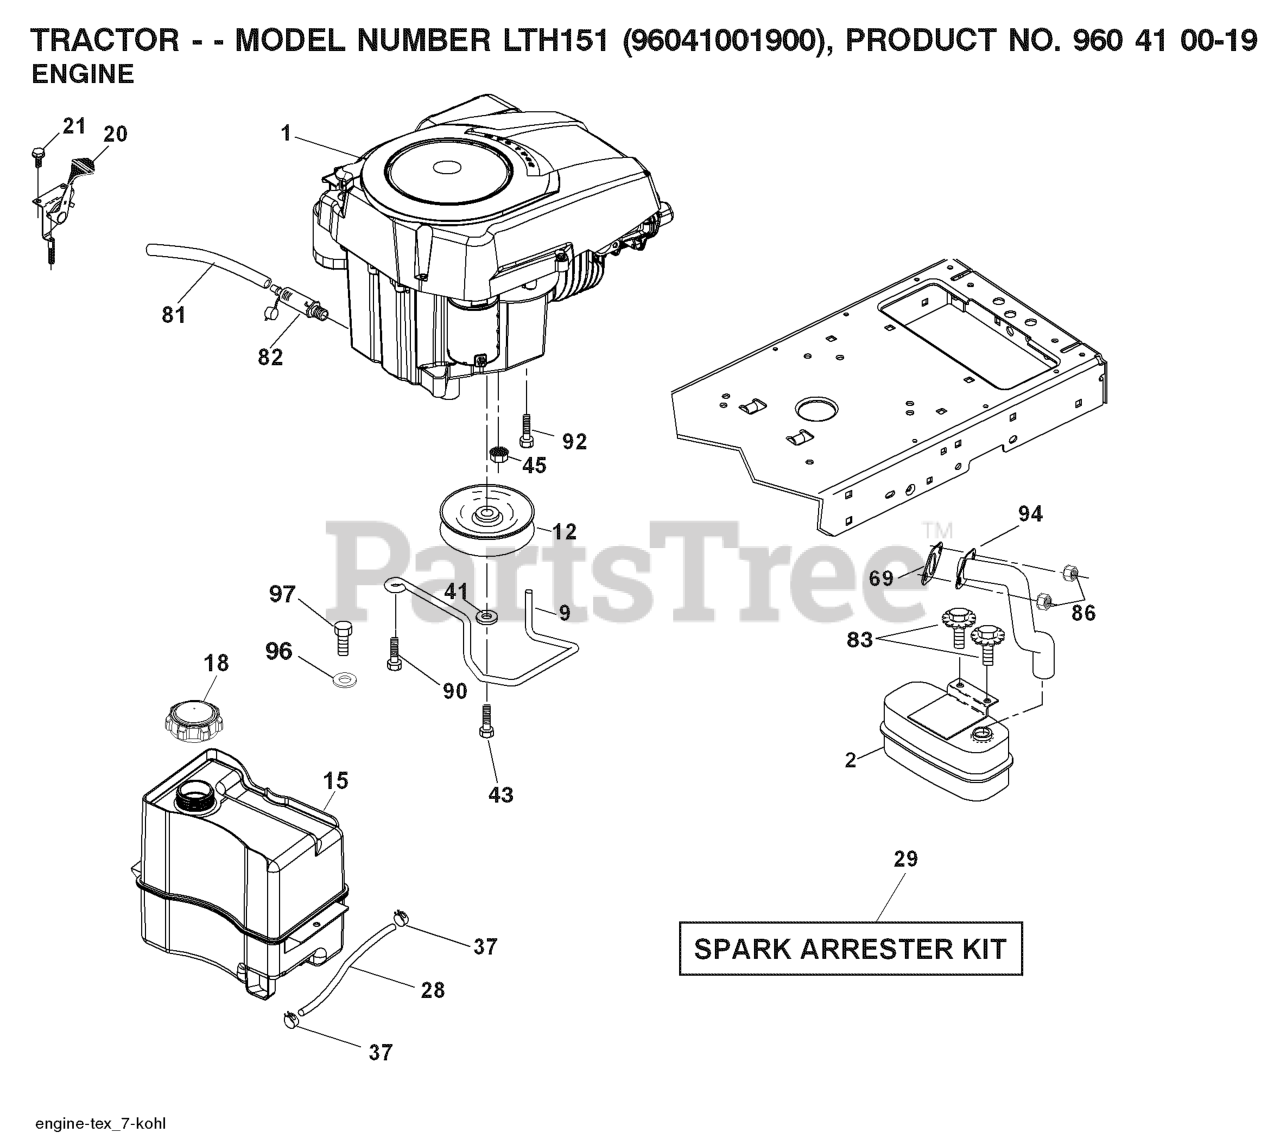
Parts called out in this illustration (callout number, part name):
2	MUFFLER.SINGLE.CYL.KOHL/B&S
9	KEEPER.BELT.ENGINE.3.25 (3 2)
12	PULLEY ENGINE
15	RP TANK FUEL FRT 1.5 GAL
18	FUEL CAP
20	CONTROL.TH/CK.COBRA.KO
21	SCREW
28	LINE.FUEL.20
29	KIT.SPARK ARRESTOR 794945 B&S
37	HOSE CLAMP
42	LOCKWASHER
45	NUT
69	GASKET.EXHAUST.KOHLER
81	TUBE, DRAIN OIL ASM.
82	PLUG DRAIN OIL EASY
83	BOLT.5/16-18UNCX3/4 W/SEMS.BLK
86	NUT.HEX.FLANGE.TOPLOCK
90	SCREW 3/8-16X1
92	SCREW 3/8-16X1
94	RP.TUBE.EXHAUST.KOHL.COURAGE
95	BOLT HEX 7/16-20X4-1/4"
96	WASHER
97	SCREW HEXWSHR 1/4-20X3/4
102	SCREW
107	SCREW.1/4-20X5/8
